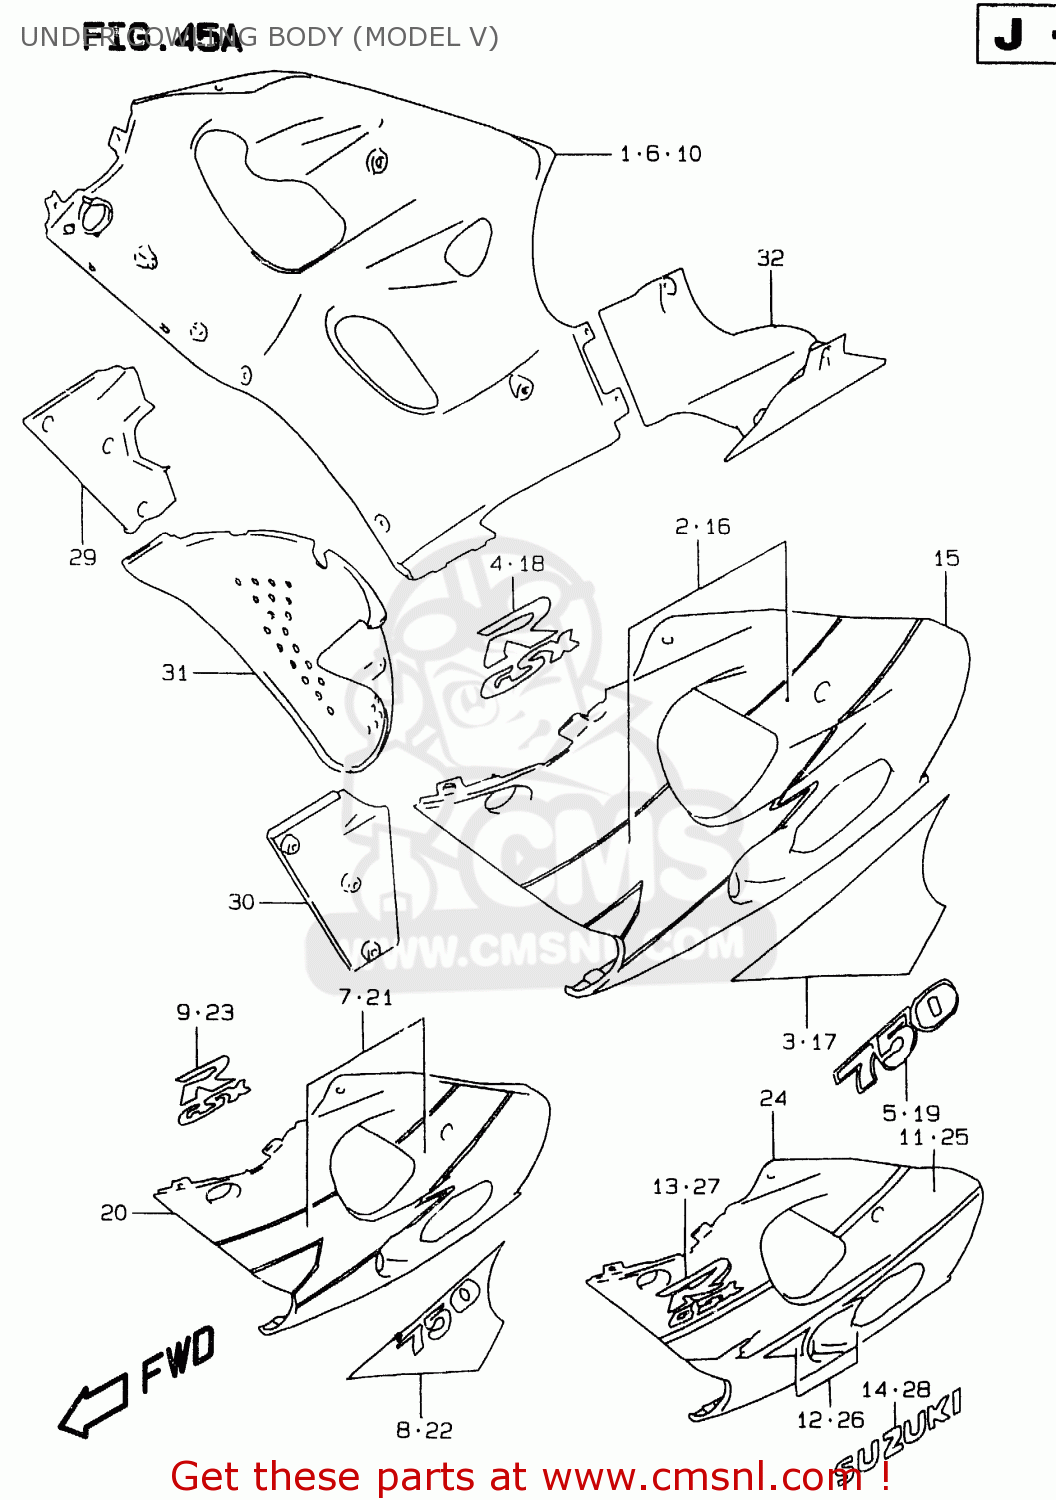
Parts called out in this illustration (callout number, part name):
1	COWLING ASSEMBLY,UNDER,RIGHT
2	TAPE SET,COWLING,UNDER,RIGHT
3	TAPE,COWLING,UNDER,RIGHT
4	EMBLEM,COWLING UNDER
5	EMBLEM,COWLING,UNDER
6	COWLING ASSY,UNDER,R
7	TAPE,C.U.R. G7
8	TAPE,COWLING,UNDER,RIGHT
9	EMBLEM,COWLING UNDER
10	COWLING ASSEMBLY,UNDER,RIGHT
11	TAPE,COWLING,UNDER,UPPER
12	TAPE SET,COWL LWR,R
13	EMBLEM,COWLING UNDER
14	EMBLEM,SUZUKI(BLUE)
15	COWLING ASSEMBLY,UNDER,LEFT
16	TAPE SET,COWL UNDER,L
17	TAPE,COWL UNDER,L
18	EMBLEM,COWLING UNDER
19	EMBLEM,COWLING,UNDER
20	COWLING ASSEMBLY,UNDER,LEFT
21	TAPE SET,COWL UNDER,L
22	TAPE,COWLING,UNDER,LEFT
23	EMBLEM,COWLING UNDER
24	COWLING ASSEMBLY,UNDER,LEFT
25	TAPE,COWL UNDER UPR,L
26	TAPE SET,COWL LWR,L
27	EMBLEM,COWLING UNDER
28	EMBLEM,SUZUKI(BLUE)
29	COWLING,UNDER INNER,R
30	COWLING,UNDER,INNER,LEFT
31	COWLING,UNDER,CENTER
32	COWLING,UNDER,REAR (SILVER)
